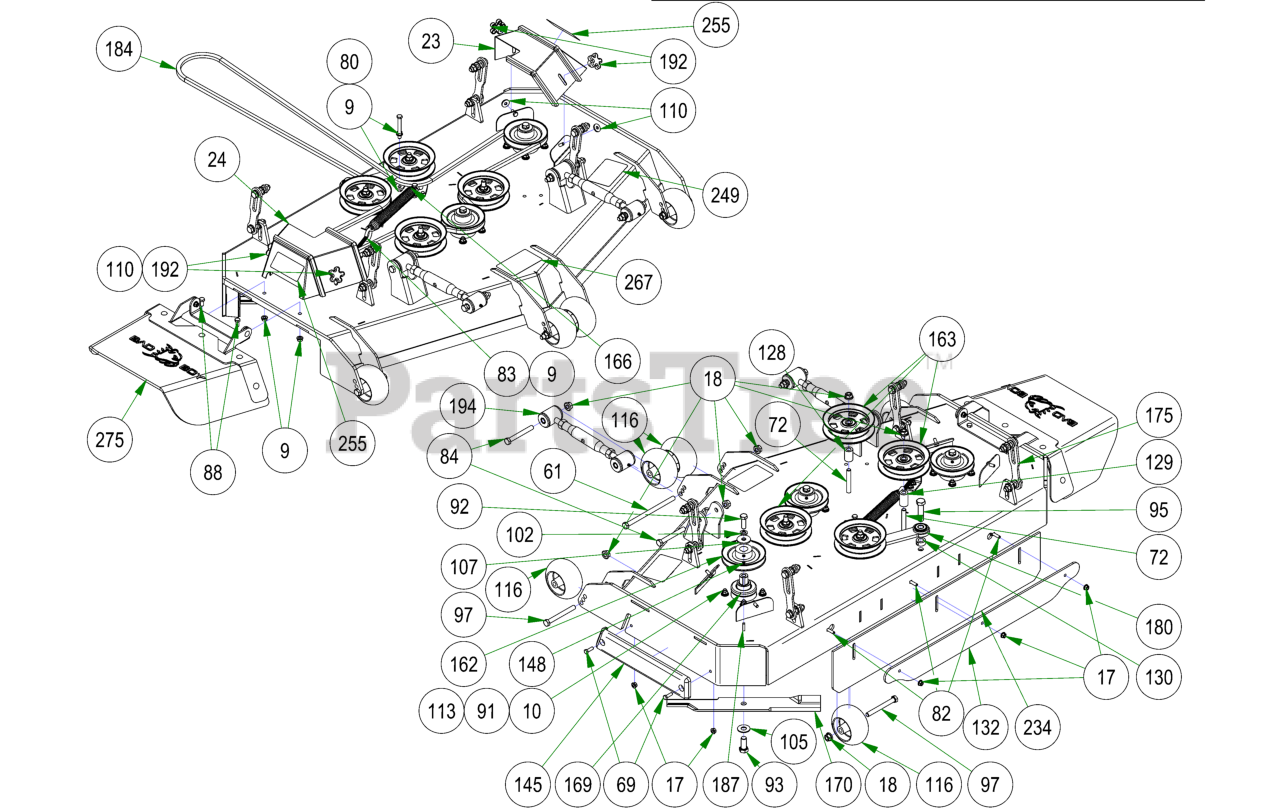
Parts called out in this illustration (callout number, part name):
9	3/8-16 HEX SERRATED FLANGE NUT HARD/ZINC
10	3/8-16 NYLON INSERT FLANGE LOCKNUT (GR.F) ZINC
12	3/8-16 HEX NUT ZINC
15	5/8-11 NYLON INSERT LOCKNUT ZINC
17	5/16-18 NYLON INSERT FLANGE LOCKNUT ZINC
18	1/2-13 NYLON INSERT FLANGE LOCKNUT ZINC
23	2019 54" Left Outlaw Gen2 Pulley Cover
24	2019 54" Right Outlaw Gen2 Pulley Cover
61	1/2-13 X 8 HEX CAP SCREW GR 5 ZINC
69	5/16-18 X 1 HEX CAP SCREW (GR.5) ZINC
72	1/2-13 X 3-1/2 HEX FLANGE BOLT (GR.8) ZINC
80	3/8-16 X 3 HEX CAP SCREW (GR.5) ZINC
82	5/16-18 X 1-1/4 CARRIAGE BOLT ZINC
83	4" 3/8-16 Eye Bolt
84	1/2-13 X 4 HEX CAP SCREW (GR.8) ZINC YELLOW
88	3/8-16 X 3/4 HEX CAP SCREW (GR.5) ZINC
91	3/8-16 X 1-1/2 HEX CAP SCREW (GR.5) ZINC
92	1/2-20 X 1-1/2 HEX CAP SCREW (GR.5) ZINC
93	5/8-18 X 1-1/2 HEX CAP SCREW (GR.8) ZINC YELLOW
95	5/8-11 X 2-1/2 HEX CAP SCREW (GR.5) ZINC
97	1/2-13 X 4-1/2 HEX CAP SCREW (GR.5) ZINC
100	5/16-18 X 7/8 CARRIAGE BOLT ZINC
102	1/2 SPLIT LOCKWASHER (GR.8) ZINC/YELLOW
105	5/8 USS FLAT WASHER (1-3/4" OD) GR.8 ZINC YELLOW
107	1/2 BELLEVILLE WASHER (1-5/8 OD X .140 THK) ZINC
110	.360 ID X .983 OD X .120 THICK FLAT WASHER NYLON BLACK
113	5/16 USS FLAT WASHER (7/8 OD) ZINC
116	2019 Deck Wheel
128	.502 ID X .750 OD X 1.500 Long Spacer
129	1 3/4" Pulley Spacer
130	5/8 SOLID SHAFT COLLAR (W/1 SET SCREW) ZINC
132	61 Bolt in Baffle Deck v2 Stripping Plate
145	REVISED TRIM BUMPER_20180226
148	5/16-24 X 1/4 SOCKET SET SCREW (CUP PT) PLAIN
162	5.25" Deck Spindle Pulley
163	5-3/4 Idler Pulley
166	2019 Outlaw Gen2 Deck Spring
169	OUTLAW SPINDLE ASSEMBLY
170	54" Fusion Blade for ZT/Mav/Outlaw/Revolt
173	2019 Deck Eye Bolt Tab
175	Deck Hanger Assembly
180	2019 Rebel Rogue Deck Idler
184	B165 Belt-60 54" deck Outlaw
187	1/4 X 1 SQ MACHINERY KEY 1018 STL PLN
192	5/16" Knob
194	Turnbuckle
209	2019 Sloped 54" Deck
234	R Series Rubber For Deck
249	2018 54" Deck Decal
255	Danger Decal-Spindle/Discharge
267	2019 Rebel & Rogue Deck Belt Route Decal
275	2019 Outlaw Gen2 Chute Assembly
